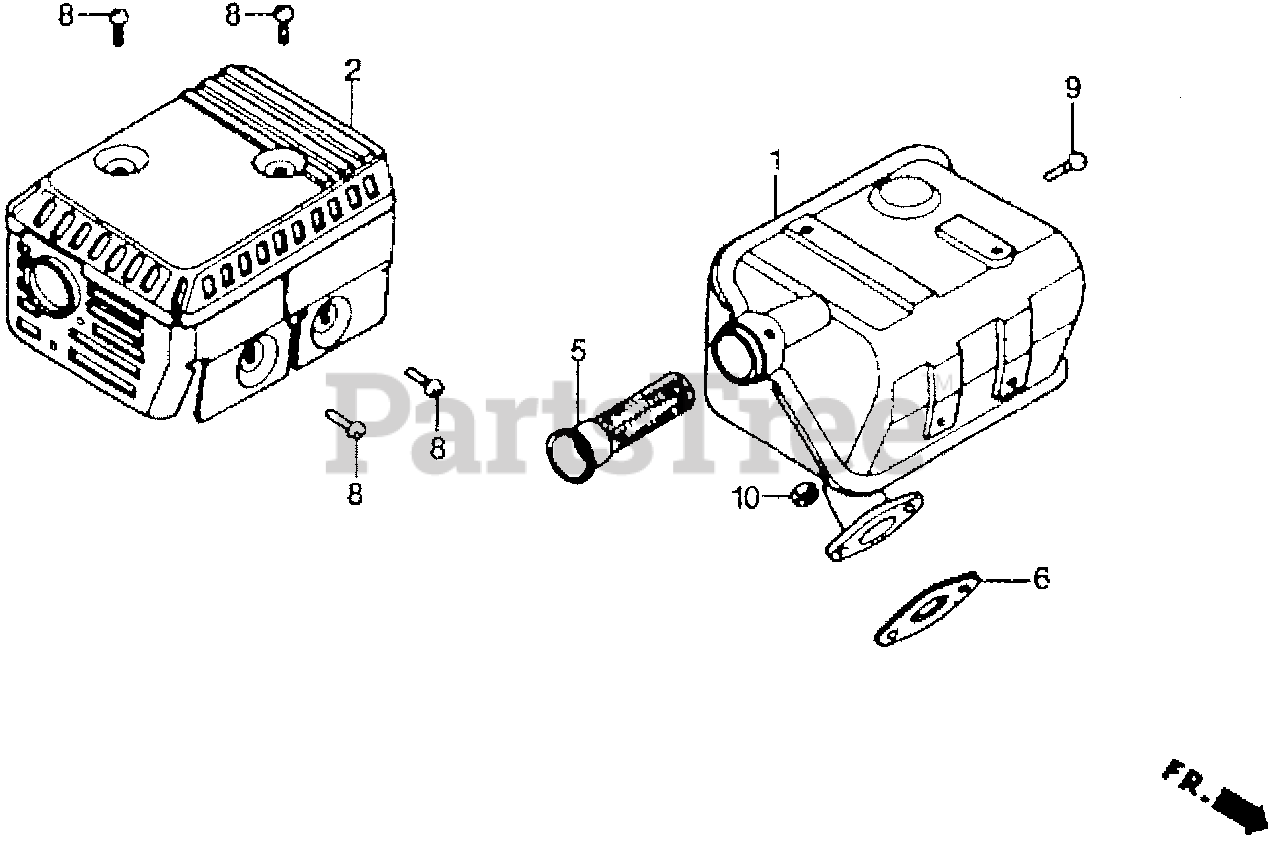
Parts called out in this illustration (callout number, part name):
1	MUFFLER
2	PROTECTOR, MUFFLER
5	ARRESTER, SPARK
6	GASKET, MUFFLER
8	SCREW, TAPPING (5X8)
9	SCREW, TAPPING (4X6)
10	NUT, HEX. (8MM)
